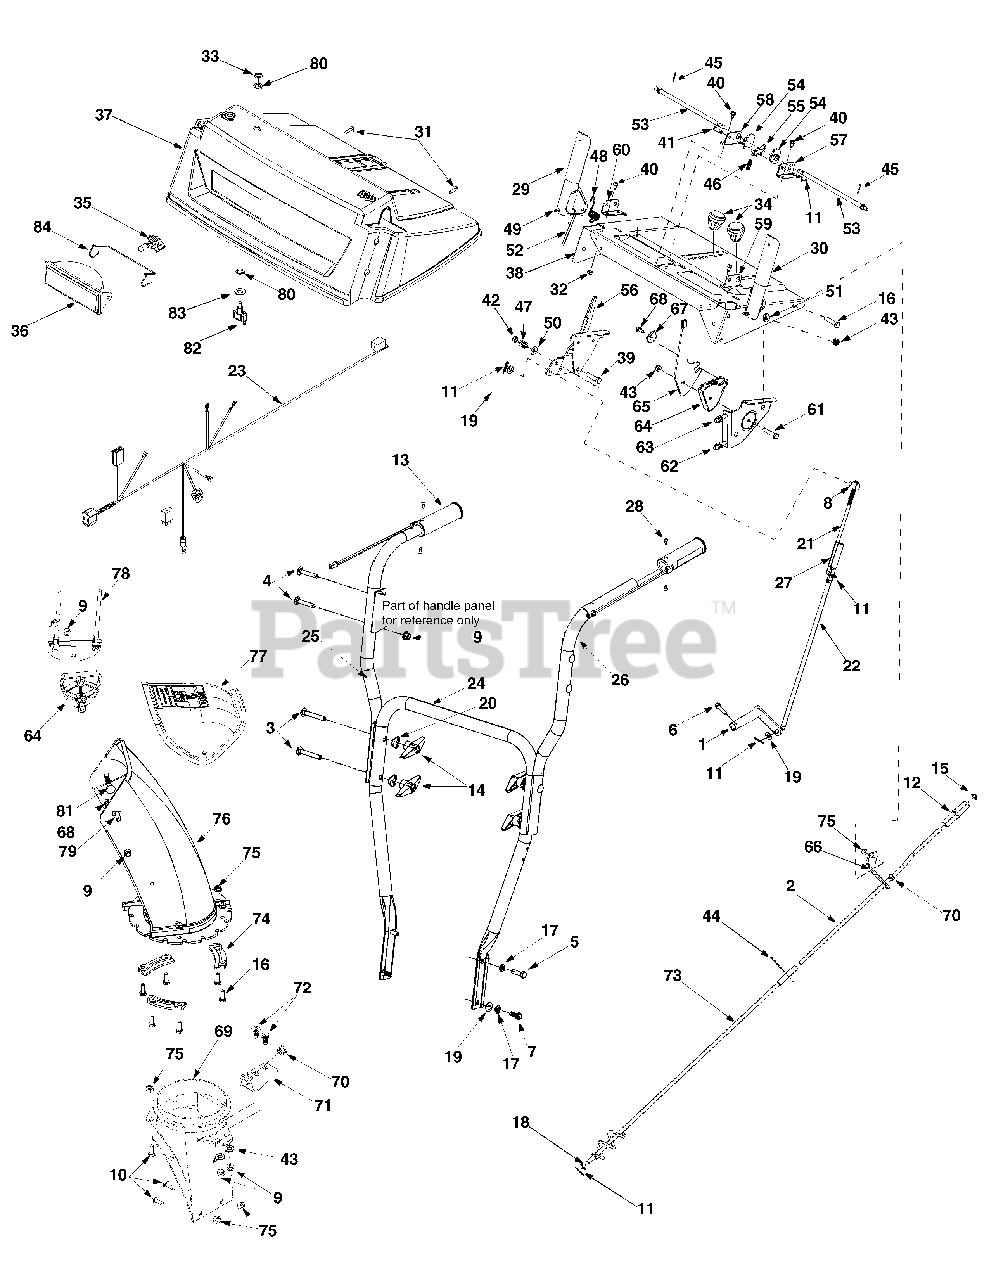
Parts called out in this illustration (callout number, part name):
3	Carriage Screw 5/16-18 x 2.25
4	Carriage Bolt 5/16-18 x 1.75
5	Hex Bolt 5/16-18 x 1.0
6	Tt Screw 1/4-20 x 1.0
7	Hex Bolt 5/16-18 x 0.75
8	Ferrule
9	Flange Lock Nut
10	Carriage Screw, 1/4-20 x.75
11	Hairpin Clip
12	Chute Directional Control Knob
13	Heated Grip
14	Handle Knob Assembly
15	Push Cap
16	Hex Screw, 1/4-20 x 1.00
17	Lock Washer
18	Flat Washer
19	Flat Washer
20	Saddle Washer
21	Upper Shift Rod
22	Lower Shift Rod
23	Heated Grips Harness Ass’y
28	Screw, #10-16 x.625
29	Handle Engagement Assembly RH
30	Handle Engagement Assembly LH
31	B Screw #10-16 x 0.625
32	Hex Sems Nut 1/4-20
33	Jam Nut, 15/32-32
34	Shift Knob
35	Halogen Lamp, 50W, 12V
36	Lamp Housing
37	Handle Panel
39	Hex Bolt 3/8-24 x 1.5
40	TT Screw 1/4-20 x 0.5
41	Clevis Pin
42	Jam Lock Nut 3/8-24
43	Flat Washer,.349 x.879 x.063
44	Click Pin
45	Cotter Pin
46	Compression Spring
47	Compression Spring
48	Torsion Spring
49	Rubber Bumper
50	Bell Washer
51	Flat Washer
52	Drive Cable Z- Fitting
53	Cam Rod
54	Handle Lock Cam
55	Handle Lock Pawl
61	Hex Bolt 5/16-18 x 1.5
62	Chute Deflector Cable w/Clip
63	Chute Deflector Control Cable
64	Chute Cable Guide
67	Special Washer
68	Hi-Lo Screw 1/4-15 x 0.75
69	Chute Adapter
70	Plastic Bushing
72	Carriage Screw, 5/16-18 x 1.00
75	Flange Lock Nut 1/4-20
76	Lower Chute
77	Upper Chute
79	Carriage Bolt 5/16-18 x 1.0
80	Toggle Switch Lock Ring
81	Carriage bolt 5/16-18 x 1.5
82	Single Throw Toggle Switch
83	Flat Washer
84	Headlight Retainer
